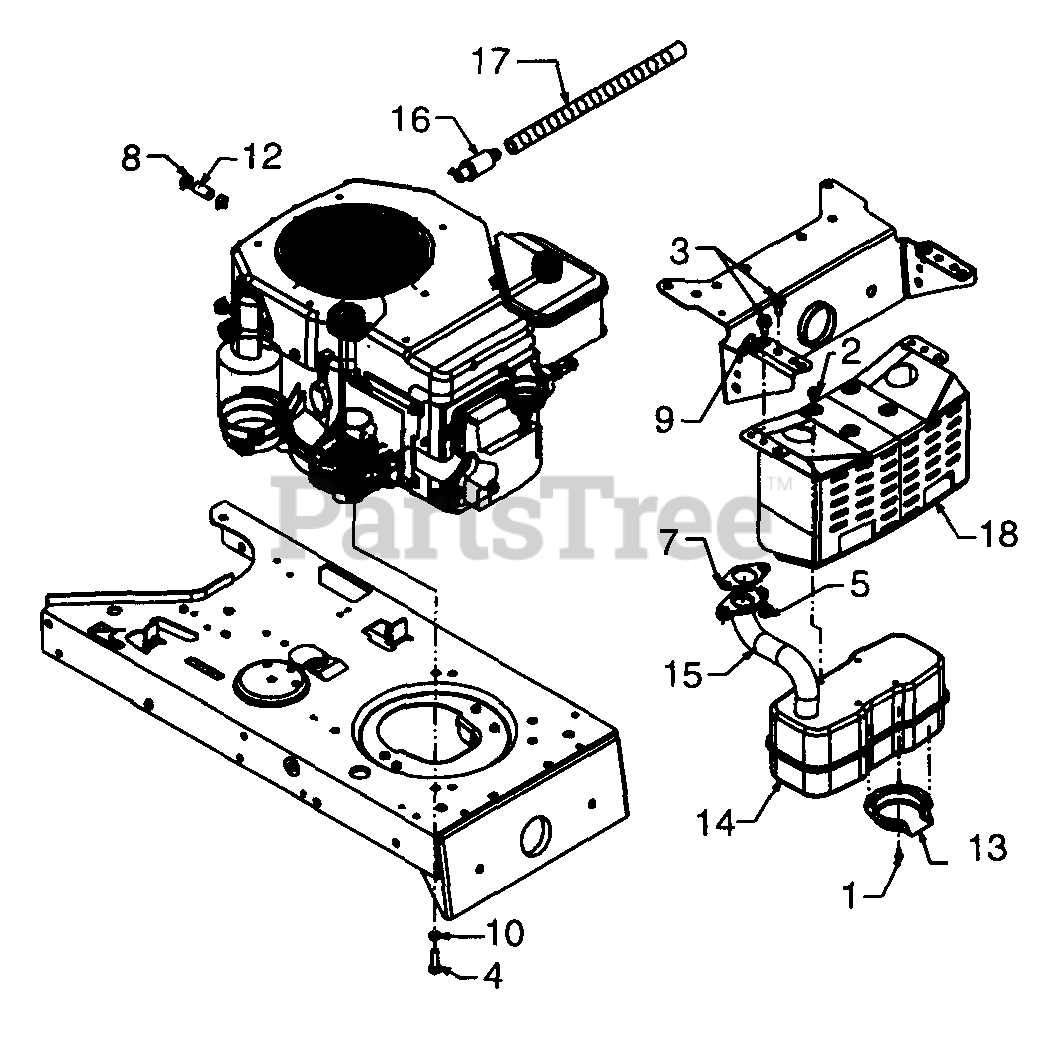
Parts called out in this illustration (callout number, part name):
1	Hex Tap Scr. #8-32 x .38" Lg.
2	Hex Wash. TT-Tap Scr. 1/4-20 x 5" Lg.
3	Hex Wash. TT-Tap Scr. 5/16-18 x .62"
4	Hex Bolt M8 x 1.25
5	Hex Flange Nut M8 Thd.
7	Exhaust Gasket
8	Hose Clamp
9	Clamp
10	External L-Wash. 5/16" I.D.
12	Fuel Line 12" Lg.
13	Muffler Deflector
14	Muffler
15	Exhaust Pipe
16	Oil Drain
17	Oil Drain Hose
